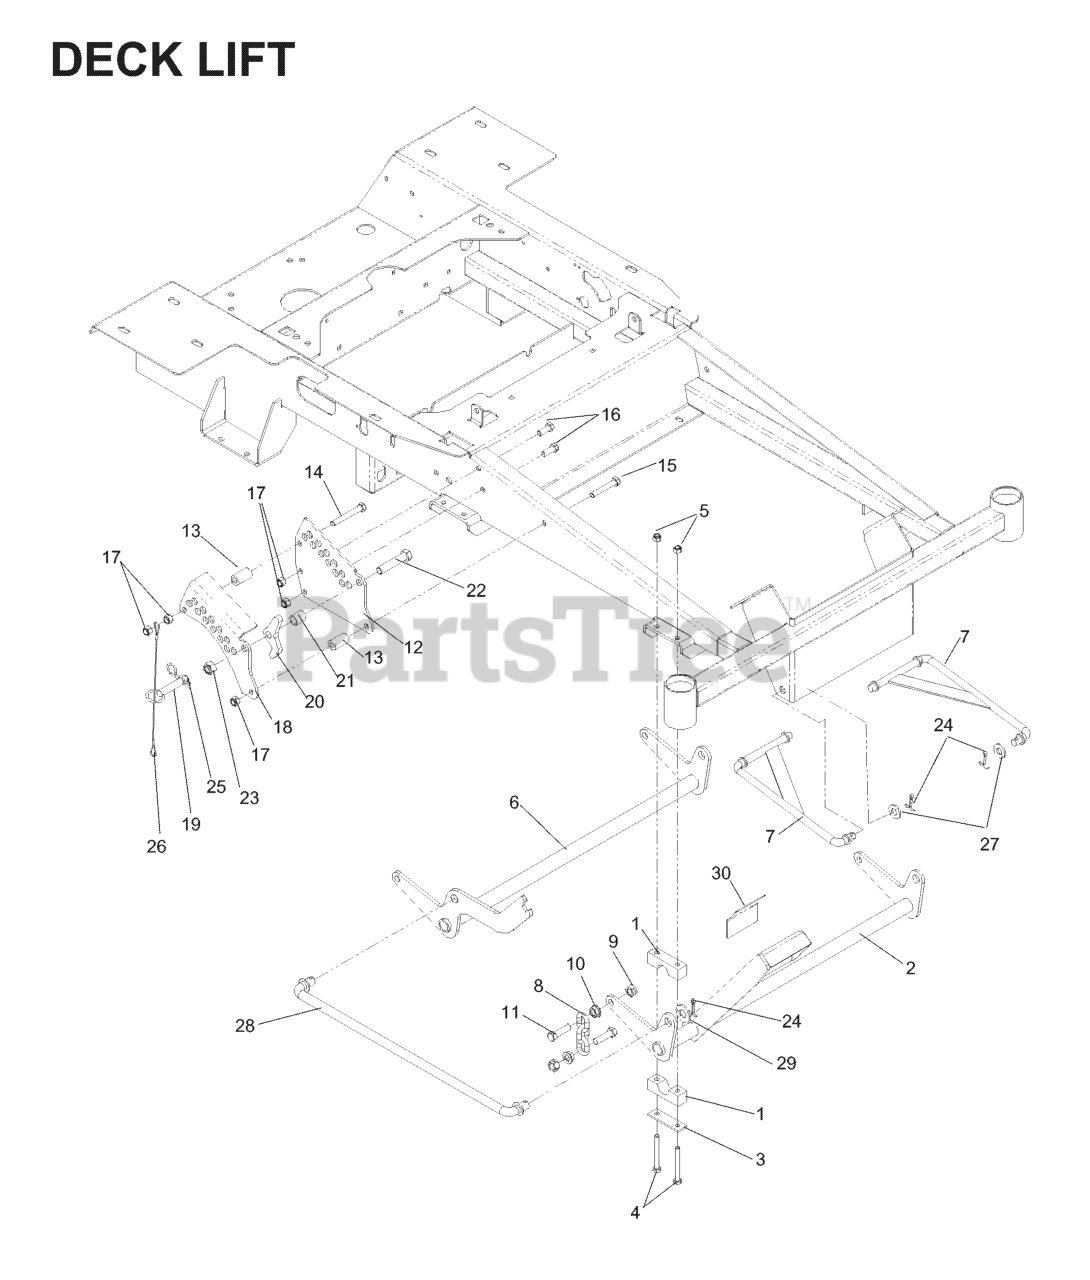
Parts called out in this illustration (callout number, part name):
1	PILLOW BLOCK
2	FRONT LIFT SHAFT
3	REINFORCEMENT BAR
4	HCS 5/16C X 2-3/4
5	NUT 5/16 NYLOC
6	LIFT SHAFT, REAR
7	STRUT LINKAGE
8	LIFT CHAIN - 3 LINK
9	NUT 7/16C CENTERLOCK
10	NUT 7/16C WHIZ
11	HCS 7/16C X 1 1/2
12	HEIGHT ADUST PLATE
13	DECK LIFT SPACER
14	SCREW 3/8C X 2 3/4 HEX CAP
15	HCS 3/8C X 2 1/4
16	HCS 3/8-16X1.GRD.5.ZD
17	NUT 3/8-16 NYLOC
18	HEIGHT ADJUST PLATE, OUTER
20	PAWL, STOP
22	HEX SCREW 1/2-13 X 2.5" GR 5
23	NUT 1/2-13 HEX NYLOC ZD
24	COTTER PIN
25	HAIRPIN #4
27	WASHER 1/2" FLAT
28	CROSS LINK
29	WASHER 5/8 FLAT
30	ANTI-SKID PAD
